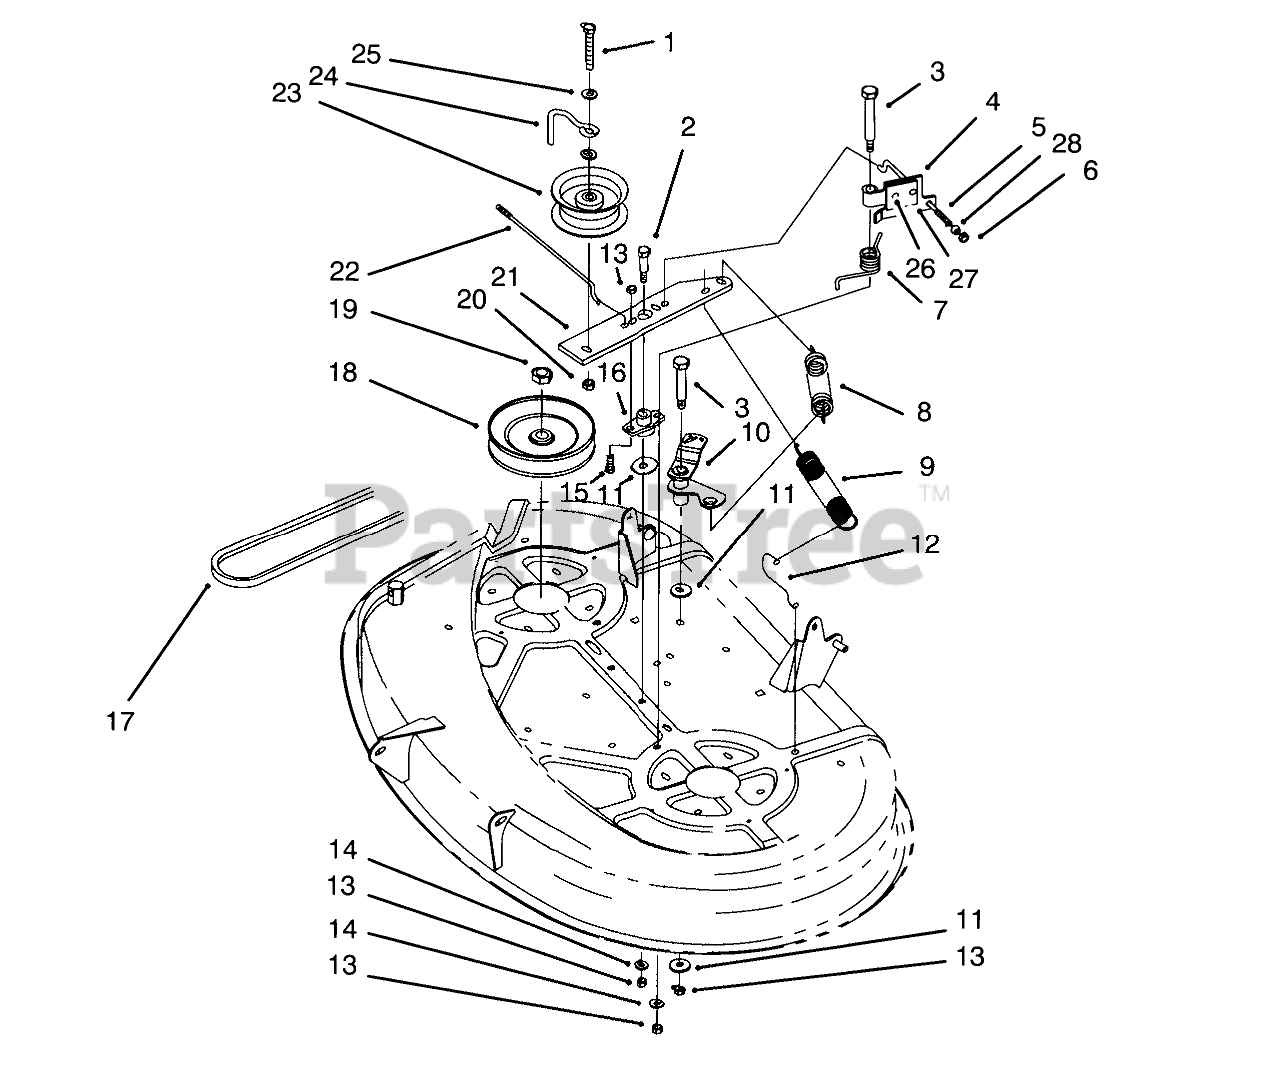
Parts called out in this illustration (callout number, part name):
1	SCREW-HH
2	SCREW-SHOULDER, HH
3	BOLT-SHOULDER
4	Brake-Deck (Incl. Ref. #26 & 27)
5	ROD-BRAKE, DECK LH
6	NUT-LOCK, NI
7	SPRING-TORSION
8	SPRING-DECK, ENGAGEMENT
9	SPRING-EXTENSION
10	Bellcrank
11	WASHER-FLAT
12	HOOK-RETURN, SPRING
13	NUT-LOCK, NI
14	WASHER-PLAIN
15	SCREW-HH
16	BUSHING-ARM, IDLER
17	BELT-V
18	PULLEY
19	NUT-HEX
20	NUT-LOCK, NI
21	Arm-Idler
22	ROD-BRAKE, DECK RH
23	PULLEY-IDLER, FLAT
24	GUIDE-IDLER, BELT
25	WASHER-FLAT
26	RIVET-BLIND
27	PAD-BRAKE
28	BALL-SWIVEL, STOP
